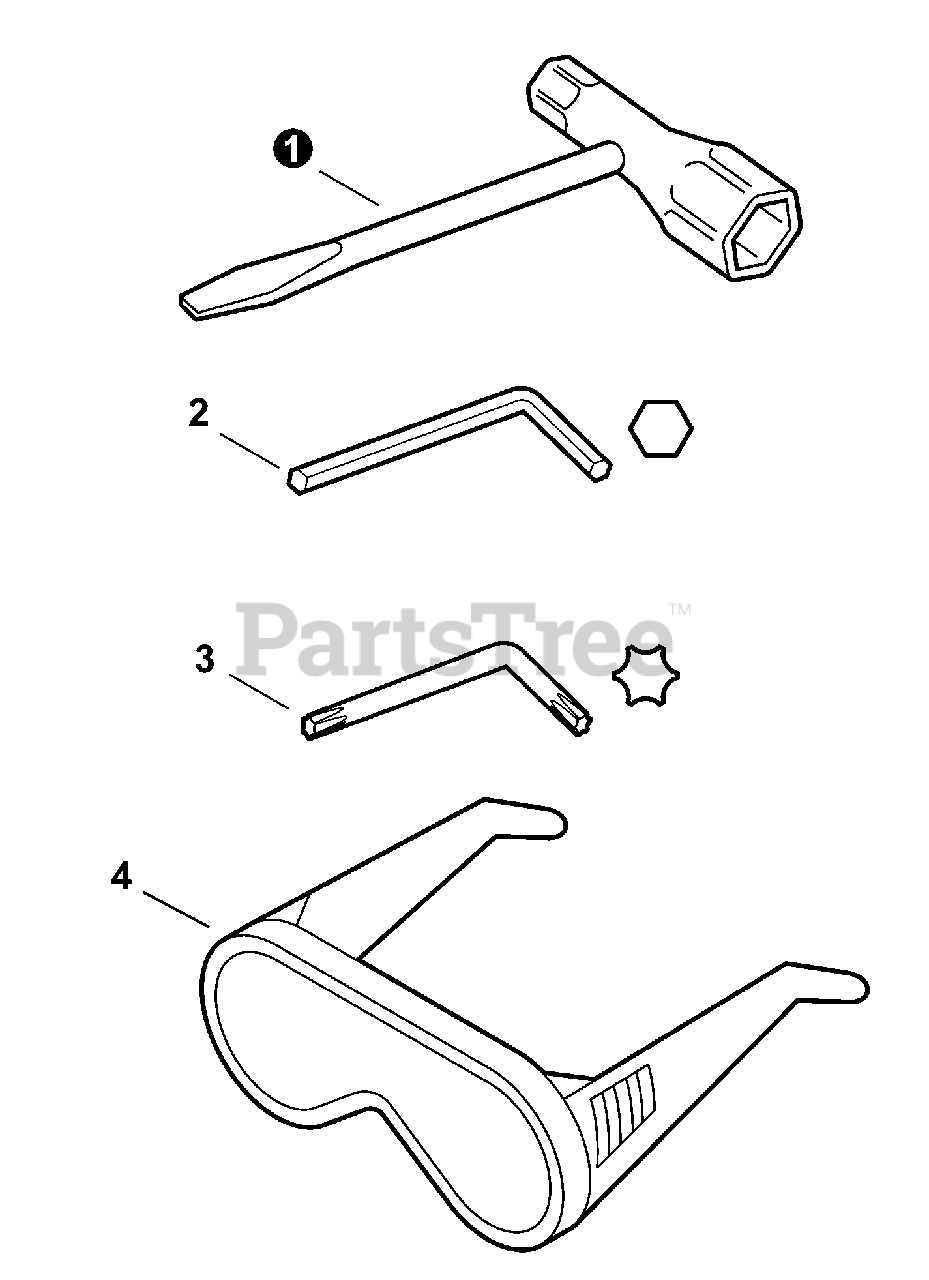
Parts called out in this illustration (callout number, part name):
1	T-WRENCH 10×19 MM
2	WRENCH, ALLEN 4 MM
3	WRENCH, T27 80×30
4	GLASSES, SAFETY
